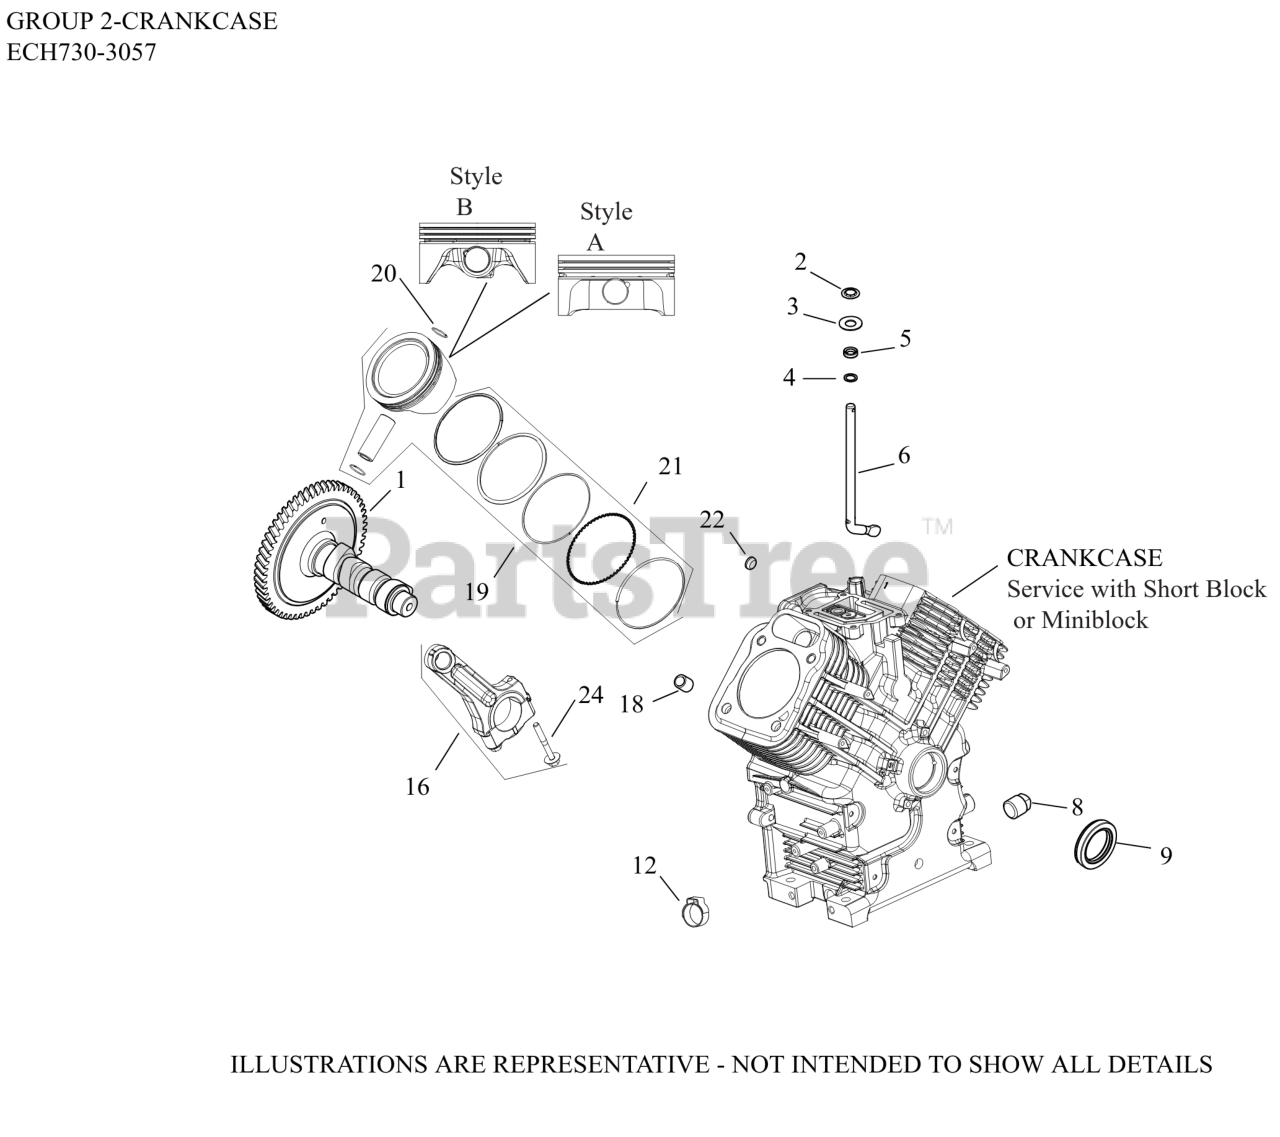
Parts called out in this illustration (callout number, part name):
1	KIT, CAMSHAFT
2	RETAINER, RING
3	WASHER, FLAT 9 MM
4	WASHER, FLAT 11/32"
4	WASHER, FLAT 1/4"
5	SEAL, GOVERNOR CROSS SHAFT
6	SHAFT, GOVERNOR CROSS
8	PLUG, HD PIPE 3/8"
9	SEAL, OIL (HELIX LIP)
16	ROD, ASSEMBLY CONNECTING
18	PIN, LOCATING
19	KIT,PSTN/RNG STYLE A(STD)(#2587406S)
19	KIT,PSTN/RNG STYLE A(.08)
19	KIT,PSTN/RNG STYLE A(.25)USE 2587411-S
19	KIT,PSTN/RNG STYLE A(.50)(#2587404S)
19	KIT,PSTN/RNG STYLE B(STD)
19	KIT,PSTN/RNG STYLE B(.08)
19	KIT,PSTN/RNG STYLE B(.25)
19	KIT,PSTN/RNG STYLE B(.50)
20	RETAINER, PISTON PIN
21	RING DISC USE PISTON ASSY PER SPEC
21	RING SET(.08)STYLE A-1.5mm Tp RING THICK
21	RING SET(.25)STYLE A-1.5mm Tp RING THICK
21	RING SET(.50)STYLE A-1.5mm Tp-(#DSC)
21	RING SET(STD)STYLE B-1.2mm Tp RING THICK
21	RING SET(.08)STYLE B-1.2mm RING THICK
21	RING SET(.25)STYLE B-1.2mm Tp RING THICK
21	RING SET(.50)STYLE B-1.2mm Tp RING THICK
22	PLUG, CUP
24	KIT, ROD BOLTS-(#25086677S)
